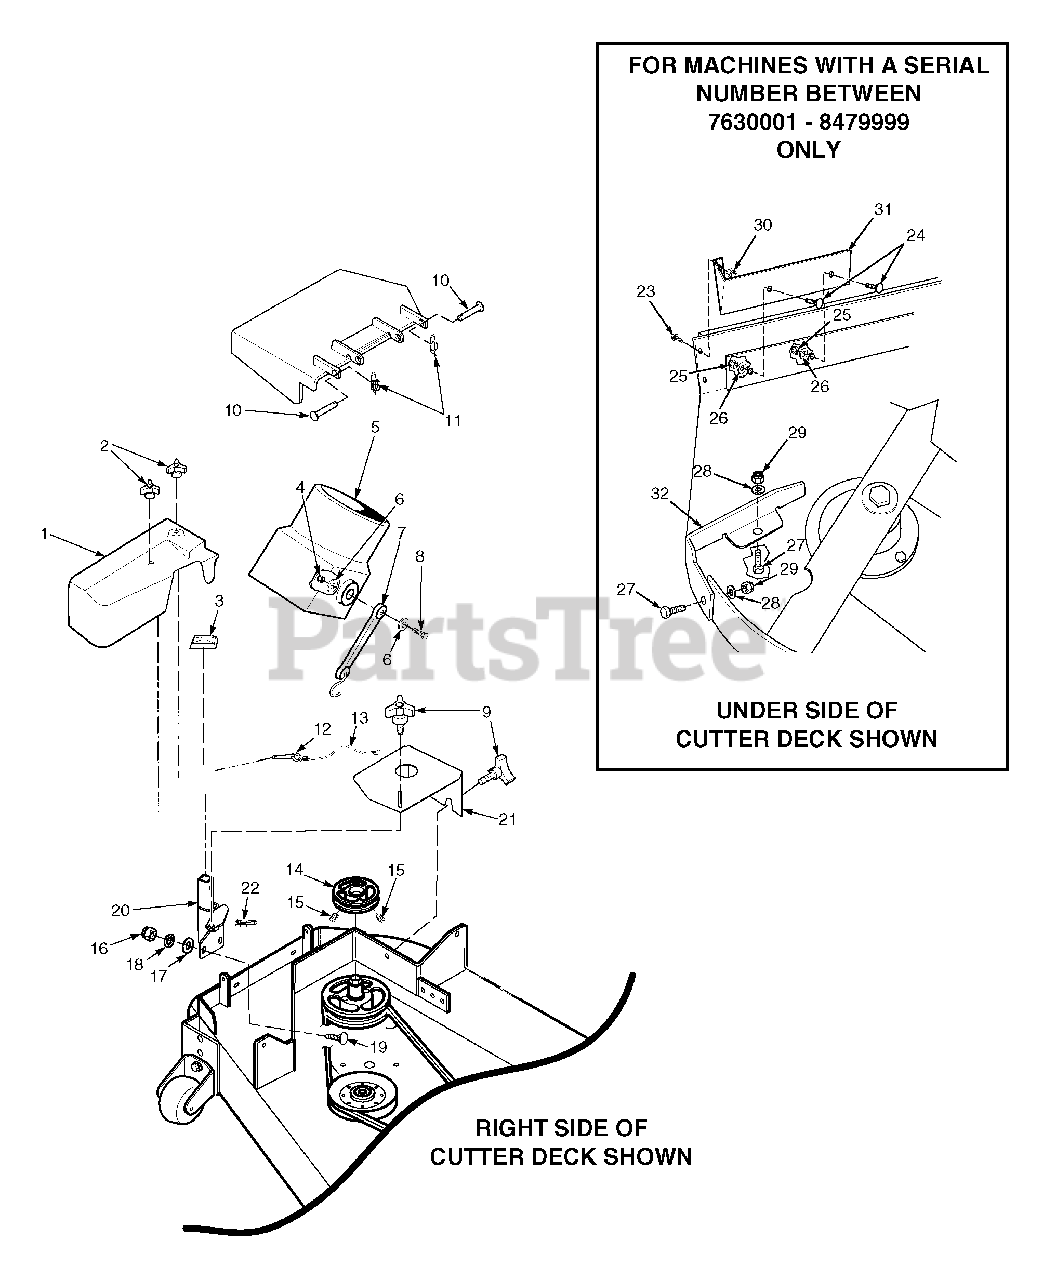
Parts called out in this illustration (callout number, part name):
1	Belt Cover, GC-STC
2	Wingnut, Plastic 3/8" Small
3	Cap, Square Vinyl
4	Nut, Elastic Stop 1/4-20
5	Adapter, Blower GC-STC
6	Flatwasher, 1/4-.312 x .750 x .065
7	Rubber Strap 7-3/4"
8	Bolt, Hex Head 1/4-20 x 1-1/4"
9	Knob W/Stud, 3/8-16 x 1-1/4"
10	Clevis Pin, 5/16 x 1-1/2"
11	Pin, Rue Cotter 5/16 Dia.
12	Pin, Ring 1/2 x 2-1/4"
13	Lanyard
14	Pulley, 4.0" Dia. 1.125 Bore
15	Setscrew, 5/16-18 x 3/8"
16	Nut, Elastic Stop 3/8-16
17	Lockwasher, 3/8"
18	Flatwasher, 3/8-.391 x .938 x .105
19	Bolt, Carr. 3/8-16 x 1-1/4" Grade 5
20	Mounting Post Weldment, Blower
21	Belt Cover
23	Bolt, Hex Head 1/4-20 x 3/4"
24	Bolt, Carriage 3/8-16 x 1"
25	Nut, Elastic Stop 3/8-16
26	Flatwasher, 3/8-.391 x .938 x .105
27	Bolt, Hex Head 5/16-18 x 1"
28	Flatwasher, 5/16-.375 x .875 x .083
29	Nut, Elastic Stop 5/16-18
30	Nut, Serrated Flange 1/4-20
31	Baffle, 48"
32	Baffle, Turbo 48" Deck
